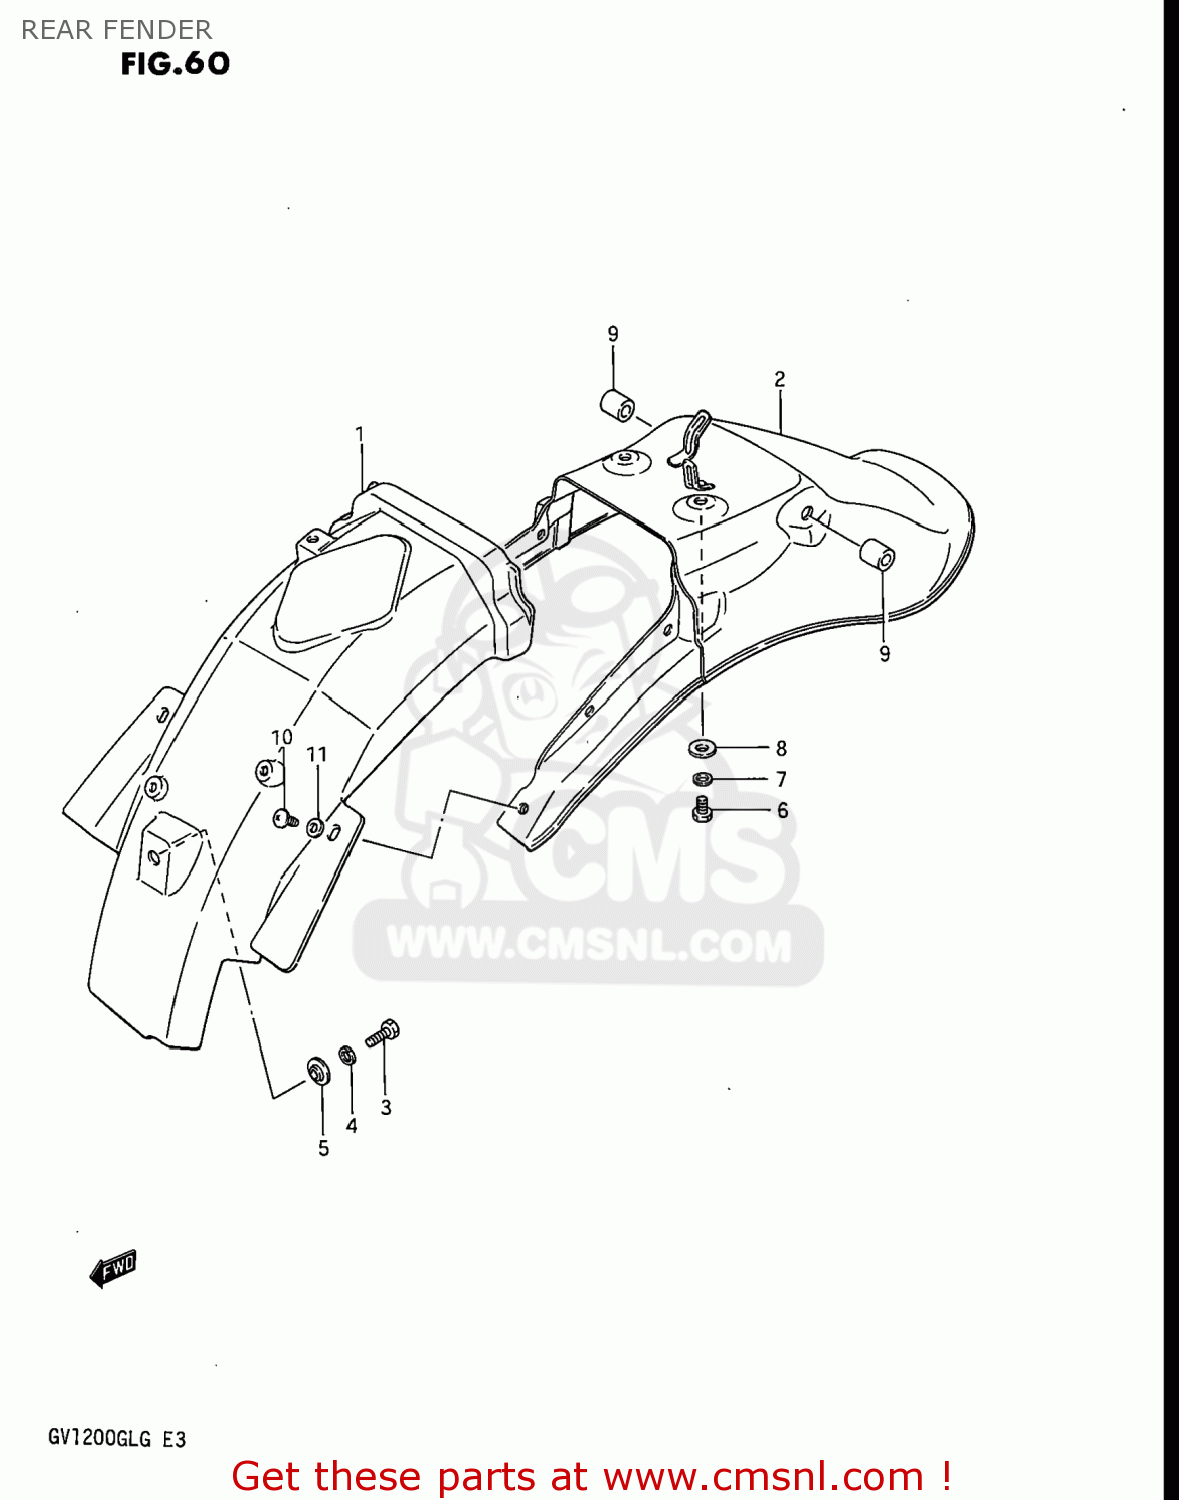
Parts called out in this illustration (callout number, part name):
1	BODY,REAR FENDER,FRONT
2	FENDER,REAR
3	BOLT
4	WASHER,LOCK
5	WASHER
6	BOLT
7	WASHER,LOCK
8	WASHER, LOWER
9	SPACER(10.2X20X20)
10	SCREW 6X12
11	WASHER
